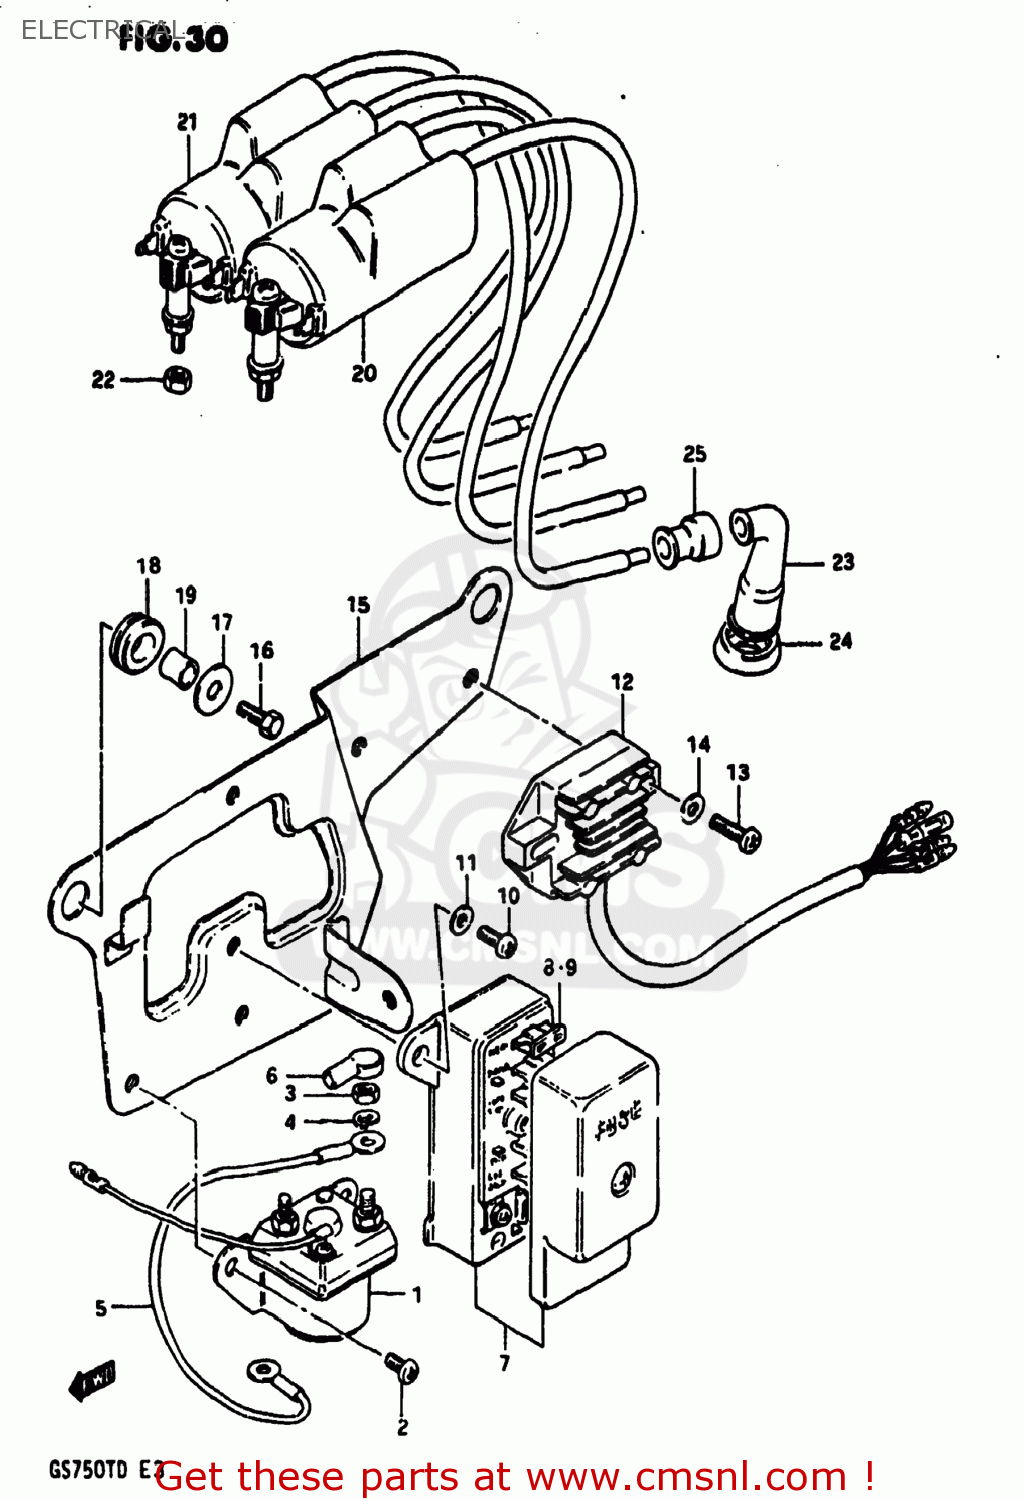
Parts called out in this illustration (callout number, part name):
1	RELAY ASSY,STARTING MOTOR
2	SCREW
3	NUT 6MM
4	LOCK WASHER
5	CORD,BATTERY MINUS
6	CAP,STARTER RELAY
7	BOX ASSEMBLY,FUSE
8	FUSE(10A)
9	FUSE(15A)
10	SCREW 6X12
11	WASHER
12	RECTIFIER ASSEMBLY
13	SCREW
14	WASHER
15	HOLDER COMP,ELECTRONIC PARTS
16	BOLT, UPPER
17	WASHER (6.5X22X1.6)
18	CUSHION
19	SPACER (7X9X7)
20	COIL ASSEMBLY,IGNITION
21	COIL ASSEMBLY,IGNITION
22	NUT
23	CAP ASSY,SPARK PLUG
24	SEAL,SPARK PLUG
25	SEAL,SPARK PLU
